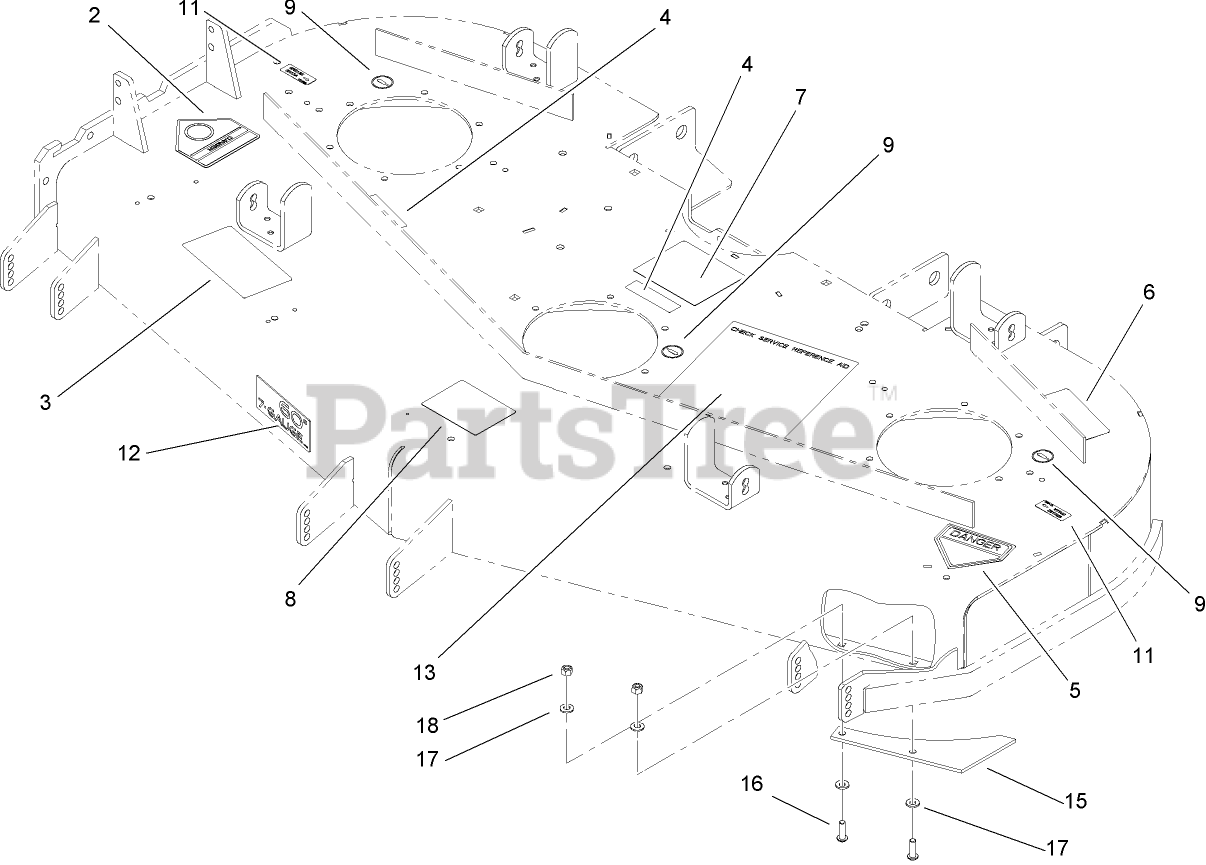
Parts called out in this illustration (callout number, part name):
2	DECAL-DANGER
3	DECAL-DANGER, THROWN OBJECT
4	DECAL-COVER, MISSING
5	DECAL-DANGER
6	DECAL-TORQUE
7	Decal-Routing, Belt
8	DECAL-SCALP, ANTI
9	DECAL-GREASE
11	Decal-Grease
13	Decal-Service, Check
15	PLATE-TURBO
16	SCREW-HSBH
17	WASHER-SPRING
18	NUT-LOCK, NI
